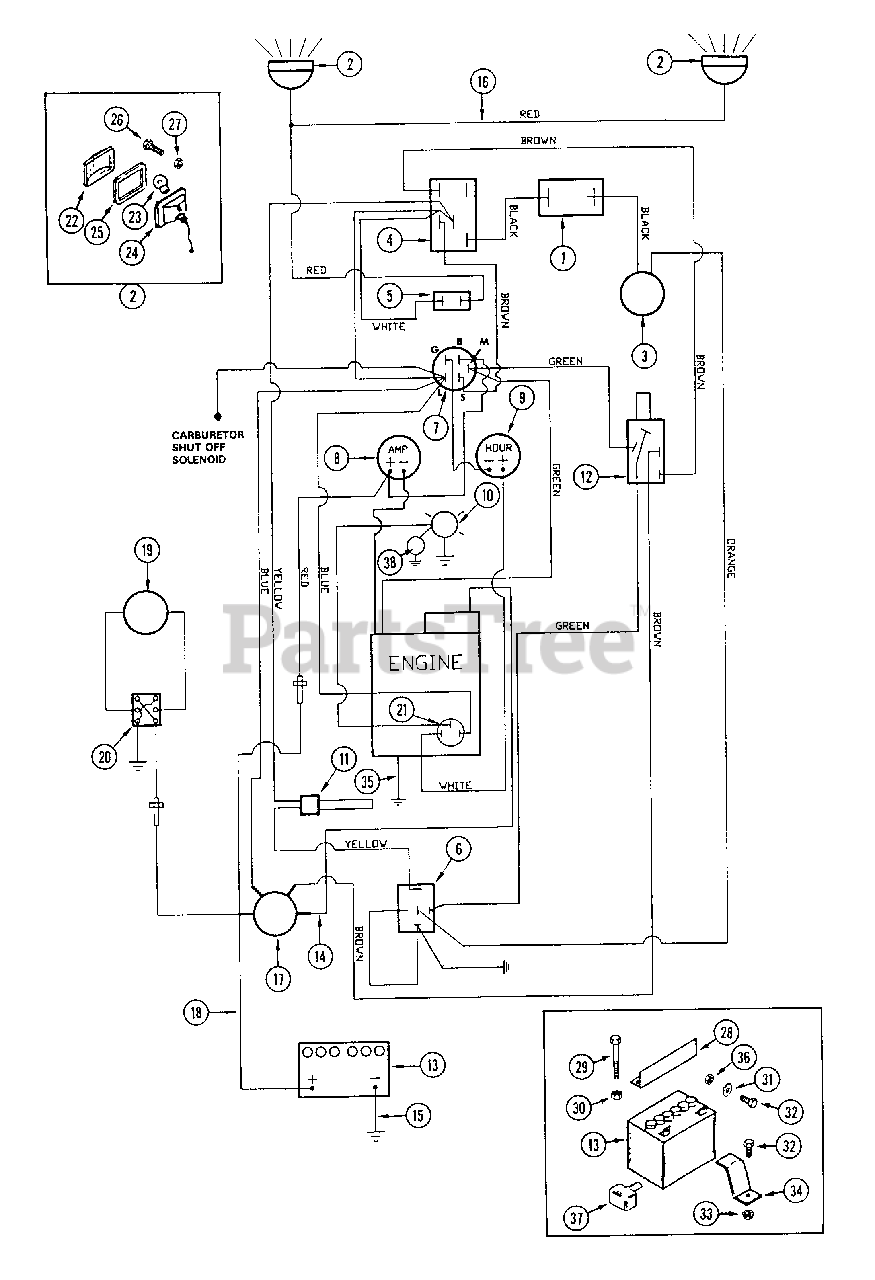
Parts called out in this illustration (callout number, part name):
1	BREAKER - circuit, 10 amp
2	HEADLIGHT
3	CLUTCH - PTO, electric
4	SWITCH - PTO
5	SWITCH - headlight
6	RELAY
7	SWITCH - ignition
12	SWITCH - safety
13	BATTERY - 12 volt
14	WIRE - starter
15	CABLE - ground
16	WIRE - headlight
17	SOLENOID - starting
18	WIRE - battery positive to solenoid
19	ACTUATOR - electric lift
20	SWITCH - deck lift
21	SWITCH - oil light
22	LENS - headlight
23	BULB - headlight
24	RECEPTICAL - headlight
25	GASKET - headlight
26	BOLT - 1/4" - 20 x 1"
27	NUT - 1/4" - 20
28	BRACKET - battery hold down
29	BOLT - 1/4" - 20 x 7"
30	NUT - 114" - 20 lock
31	WASHER - 1/4"
32	BOLT - 1/4" - 20 x 3/4"
33	NUT - 1/4" - 20 flange lock
34	PROTECTOR - battery post
35	WIRE - engine ground
36	NUT - 1/4" - 20
37	COVER - terminal
38	HORN - warning
